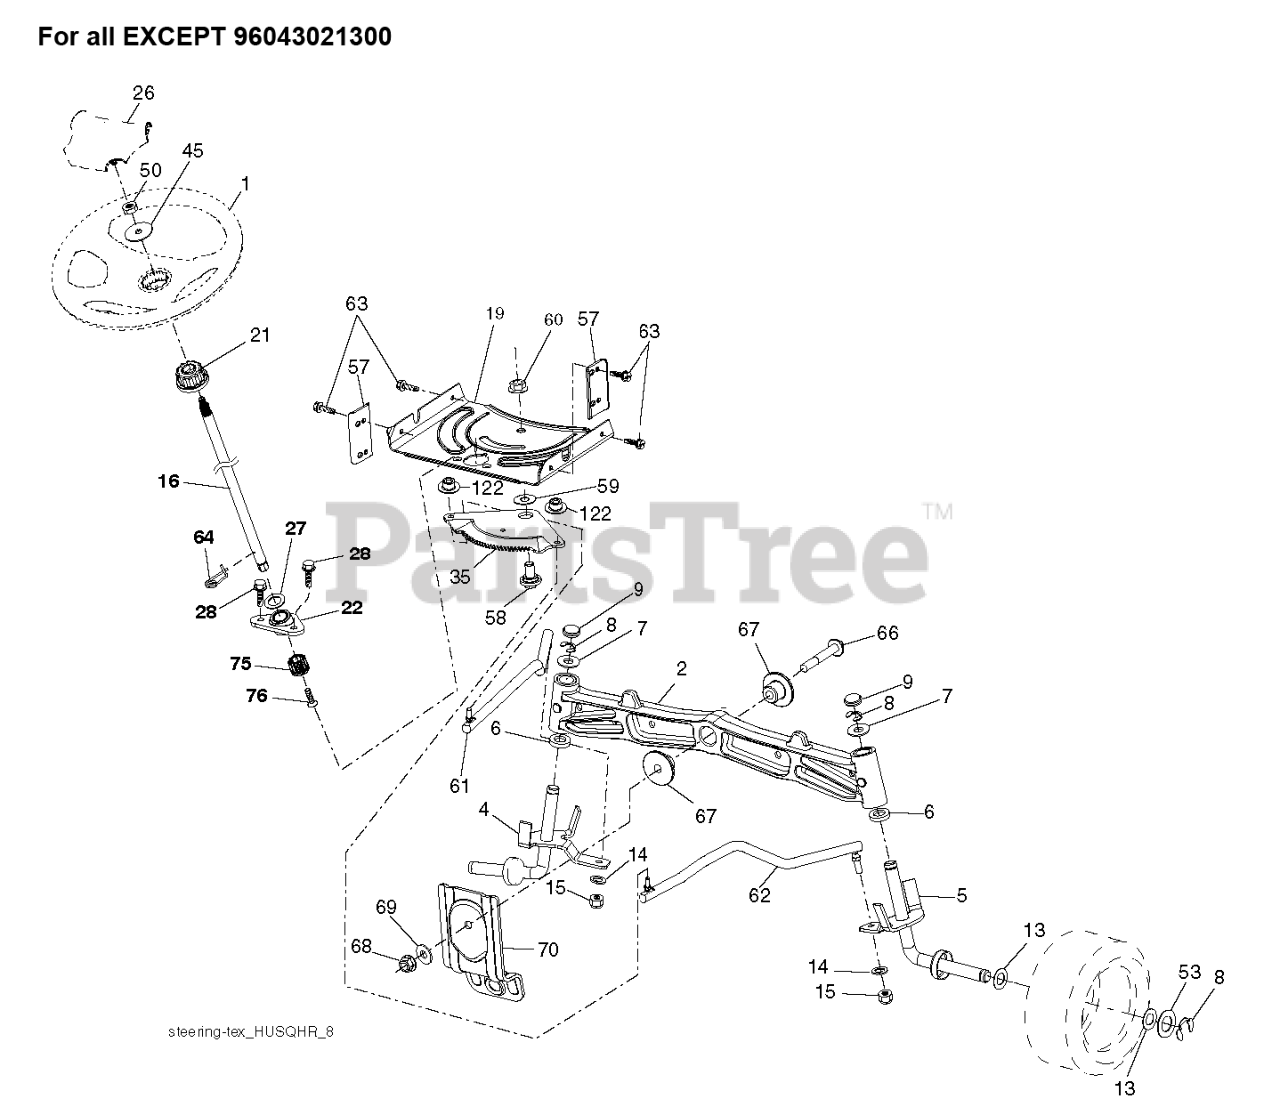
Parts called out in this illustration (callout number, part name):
1	WHEEL.STEER.HUSQ.SR.498.OVMLD
1	Service Kit
2	AXLE.CAST.IRON
2	AXLE.SVC.ASM CAST IRON.TEX
4	SPINDLE.WELDED.LH.15"TEX.X431
5	KIT.SPINDLE.WELDED.RH.15"TEX
6	WASHER THRUST
9	CAP.SPINDLE.BLACK
15	NUT CROWNLOCK 3/8-24
16	SHAFT.STEER.2HIGH.SPLND.PLATED
16	KIT.SRVC.STEERINGSHAFT.2HISHFT
19	PLATE.STEER.DDL.NLT/NG
21	ADAPTER.WHEEL.STEER.SPLND.ALUM
21	KIT.SRVC.STEERINGSHAFT.ADAPTER
22	KIT.SRVC.STEERINGSHAFT.LWRBSHG
26	Steering
26	INSERT.CAP.WHL.STRG.HUSQ.PREM
27	Washers
27	WASHER LT
27	WASHER
28	SCREW, 3/8-16X3/4
35	GEAR.SECTOR.PLATE.DDL.
45	WASHER.3/8ID.2-3/8OD.12GA.PLTD
45	WASHER 9/16"ID, 2 3/8"OD
50	NUT.HEX.FLANGE.3/8-16.LOCKNUT
50	NUT.HEX.1/2-20
50	NUT LOCK FLG 3/8-16 UNC
53	WASHER.HARDENED
57	BRACKET.UPSTOP.TEX
58	BOLT.SHOULDER.SECTOR.P
59	WASHER.THURST.SECTOR.S
60	NUT FLANGE LOCK 5/8-11
61	DRAGLINK.LH.BALLSTUD.D
62	DRAGLINK.RH.BALLSTUD.D
63	SCREW
64	RETAINER.CLIP.SPRING.S
66	BOLT HEX FGHD 7/16-14 X 3 SERR
67	BUSHING.PM.FRONT AXLE
68	NUT.LOCK.FLANGE.7/16
69	WASHER.1.5X.505X.118
70	BRACKET.FRT.DECK.SUSP.RR.MT431
75	PINION.ZINC PLATED
76	SCREW HEAD SOCKET LRVB
122	CAP.GEAR.SECTOR.TEX
